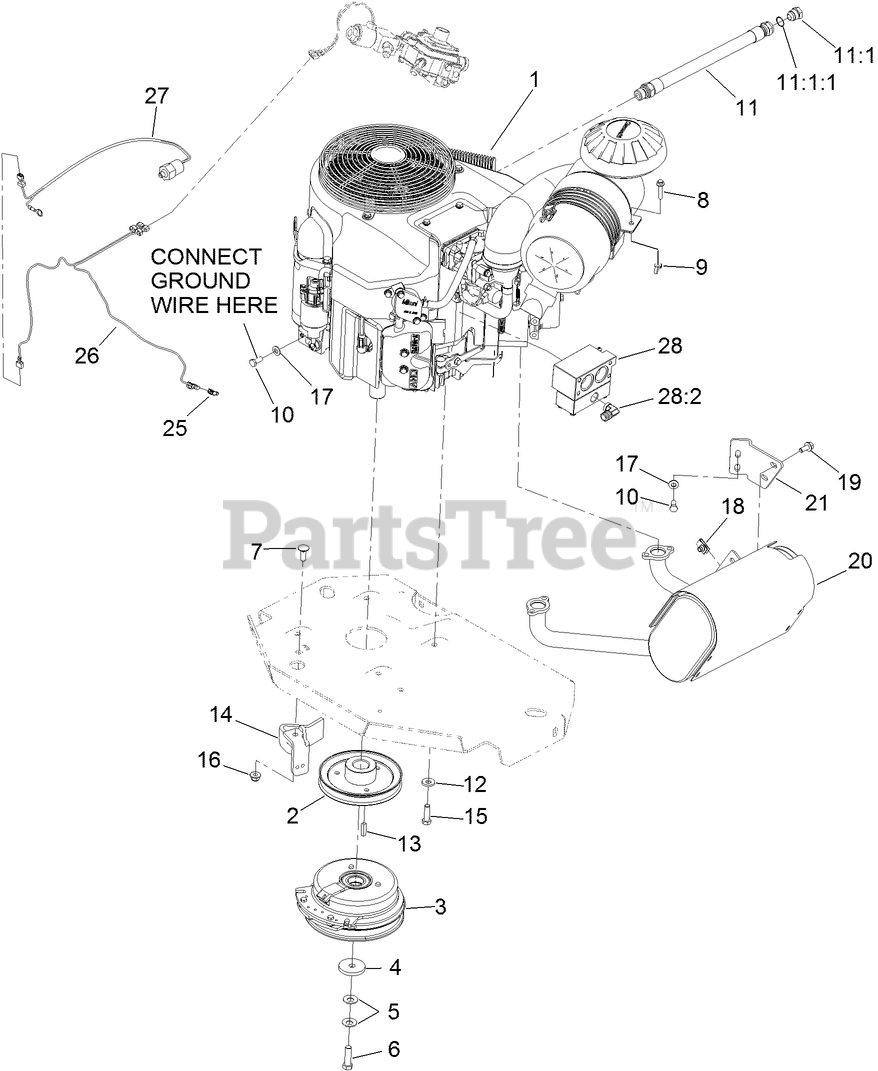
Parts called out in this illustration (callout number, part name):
2	SHEAVE
3	CLUTCH KIT
4	WASHER-CLUTCH
5	WASHER-SPRING
6	SCREW-HH, W/LOCTITE
7	SCREW-CARR
8	SCREW-HHF
9	NUT-WING
10	SCREW-HH
11	ENGINE OIL DRAIN HOSE ASM
11:1	PLUG-HH
11:1:1	O-RING
12	WASHER-BELLEVILLE
14	CLUTCH-ANCHOR
15	SCREW-HH
16	NUT-HF, NI
17	WASHER-SPRING
18	NUT-U
19	SCREW-HHF
20	MUFFLER
21	BRACKET-MUFFLER
25	TERMINAL-TAB
26	WIRE HARNESS
27	OIL PRESSURE SWITCH ASM
28	LPG MIXER ASM
